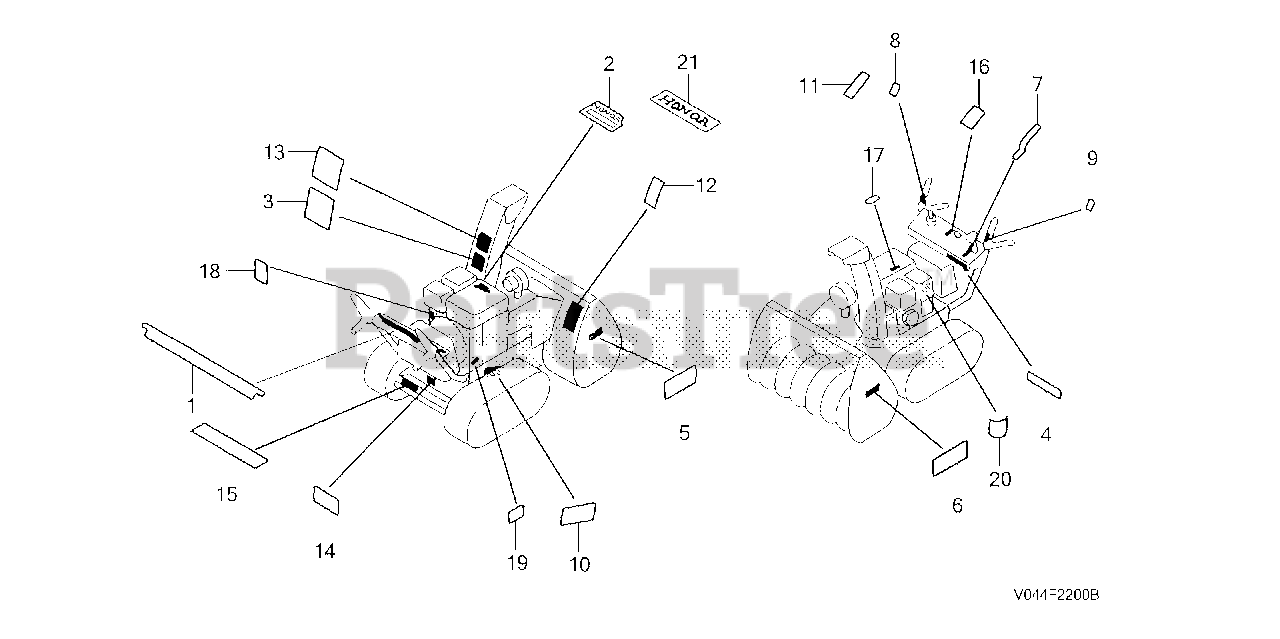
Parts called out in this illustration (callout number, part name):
1	LABEL, OPERATION (C)(ENGLISH)
2	MARK, HONDA EMBLEM
3	LABEL, WARNING (ENGLISH)
4	LABEL, WARNING FUEL (ENGLISH)
5	MARK, R. STRIPE (Z)
6	MARK, L. STRIPE (Z)
7	MARK, CHANGE INDICATION
8	MARK, AUGER CLUTCH (ENGLISH)
9	MARK, CLUTCH (ENGLISH)
10	MARK, HEIGHT ADJUSTING
11	MARK, CHUTE CONTROL OPERATION (ENGLISH)
12	MARK, HOUSING DANGER (ENGLISH)
13	MARK, DISCHARGE DANGER (ENGLISH)
14	MARK (H.S.T.)
15	MARK, INDICATION (H.S.T.)(ENGLISH)
16	MARK, THROTTLE (ENGLISH)
17	MARK, EX. CAUTION (ENGLISH)
18	MARK, FUEL INDICATION (ENGLISH)
19	MARK, OIL CAUTION (ENGLISH)
20	LABEL, OIL RECOMMENDATION (ENGLISH)
21	MARK, HONDA EMBLEM
